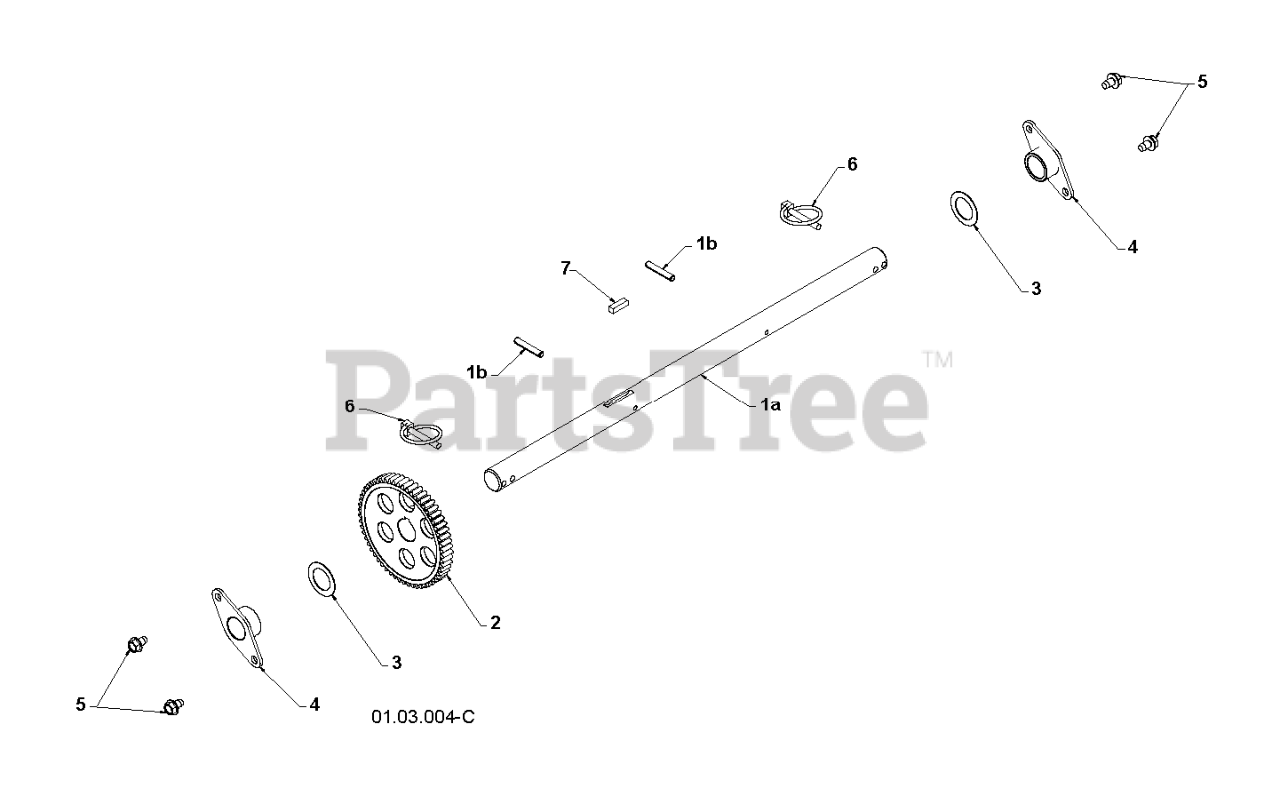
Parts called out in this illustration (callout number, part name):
1	AXLE.SHAFT.ASM.W/ROLPIN.NON-PS
2	GEAR, AXLE (58T)
3	WASHER TRUST 1"
4	BEARING, AXLE
5	Screw 5/16-18 x 1/2 Hex, Self Tapping 5/16-18 x 1/2
6	PIN KLIK, 1/4
7	KEY, SQUARE 1/4 X .875
